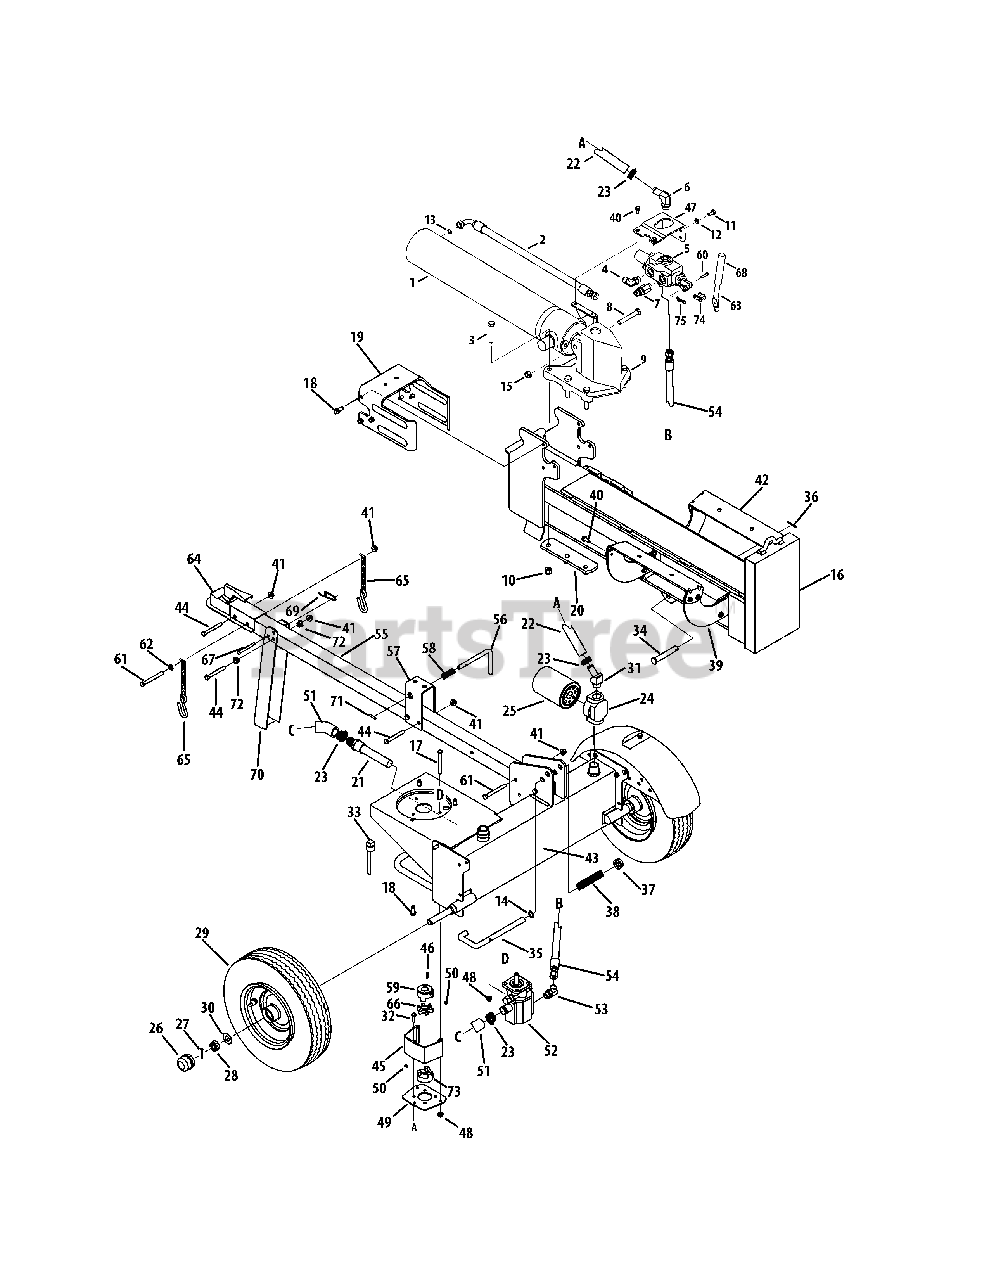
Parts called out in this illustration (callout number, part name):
1	Hydraulic Cylinder
2	Hydraulic Tube
3	Hex Cap Screw, 1.2-20 x 2.75
4	90 Degree Solid Adapter
5	Control Valve
6	Return Elbow
7	Nipple Pipe, 1.2-14
8	Hex Cap Screw, 1.2-13 x 3.25
9	Wedge Assembly
10	Hex Lock Nut, 1.2-20
11	Hex Cap Screw, 3/8-16 x .75
12	Lock Washer, 3/8
13	O-Ring, .489 ID x .070 Dia.
14	Flat Washer, .635 x.93 x.06
15	Hex Lock Nut, 1.2-13
17	Hex Screw, 5.16-18 x 3.25
18	Self Tapping Screw, 3.8-16 x 1.0
19	Dislodger Bracket
21	Inlet Filter
22	Return Hose, 3.4 x 44
23	Hose Clamp, 5.8
24	Filter Housing
25	Oil Filter
27	Cotter Pin
28	Slotted Nut, 3.4-16
29	Complete Wheel Assembly
29	Dust Seal
29	Roller Bearing
30	Flat Washer, .760 x.500
31	Hydraulic Fitting, 1 1/16 Orb x .75
32	Hex Screw, 5.16-18 x 1.00
33	Vented Dipstick
34	Clevis Pin
36	Cotter Pin
38	Compression Spring
39	Log Tray Bracket
40	Hex Washer Screw, 5.16-18 x .750
41	Flange Lock Nut, 3.8-16
43	Frame Assembly
44	Hex Bolt, 3.8-16 x 3
45	Coupling Shield
46	Square Key, 3.16h x .75
47	Outer Valve Bracket
48	Flange Lock Nut, 5.16-18
49	Rear Coupling Support Bracket
50	Set Screws
51	Hose
53	45 Degree Elbow Fitting
54	High Pressure Hydraulic Hose
55	Tongue Assembly
56	Latch Rod
58	Compression Spring
59	Coupling, .875
60	Clevis Pin
61	Hex Cap Screw, 3.8-16 x 3.50
62	Flat Washer, .375 x.738 x.063
63	Hydraulic Valve Control
64	Hitch Coupling Assembly
66	Spider Bushing
67	Clevis Pin
69	Spring Pin
71	Spiral Pin
72	Plastic Bushing, .380 ID
73	Coupling, .500
74	Valve Handle Link
75	Cotter Pin, Bow Tie
